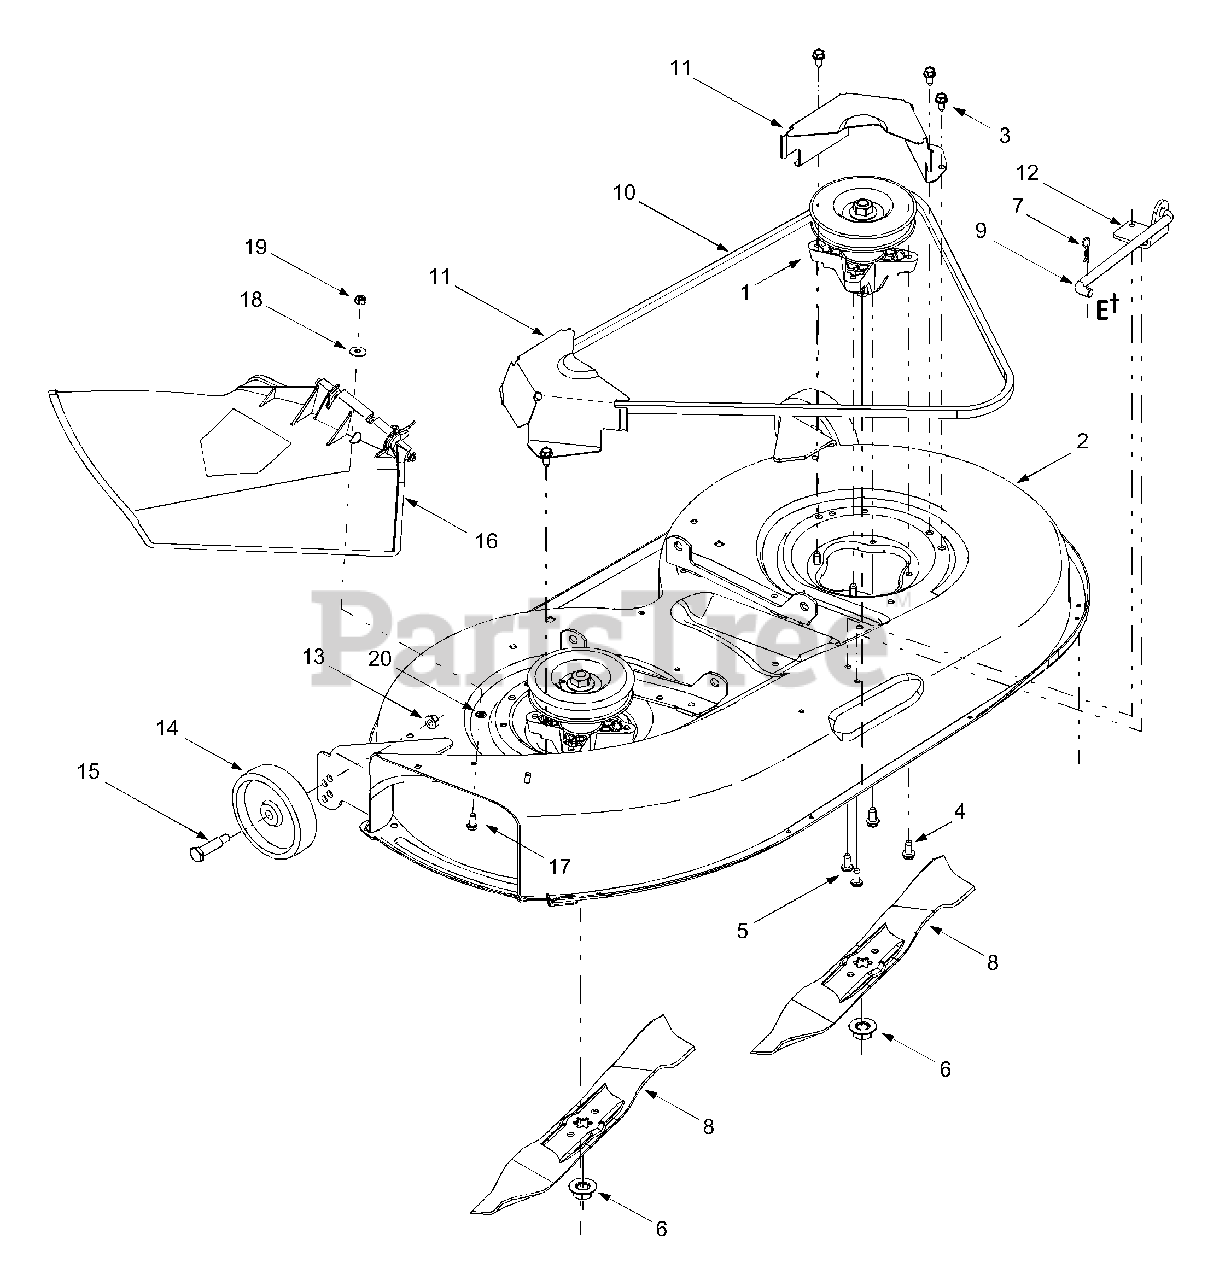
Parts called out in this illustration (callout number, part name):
1	Spindle Assembly
4	Screw, 5/16-18 x .75
5	Self-tapping Screw, 5/16-18 x .75
6	Hex Flange Nut, 5/8-18
7	Internal Cotter Pin, .080 x 1.56
8	Blade, 21.23"
9	Deck Hanger Link/Anti-sway Rod
10	Deck Belt
13	Flange Lock Nut, 3/8-16
14	Deck Wheel, 5 x 1.38
15	Shoulder Screw, .498 x 1.53
16	Discharge Chute Assembly
17	Hex Cap Screw:1/4-20 x .620
18	Bell Washer, .265 x .75 x .062
19	Hex Nut, 1/4-20
20	Push Nut, 1/4
